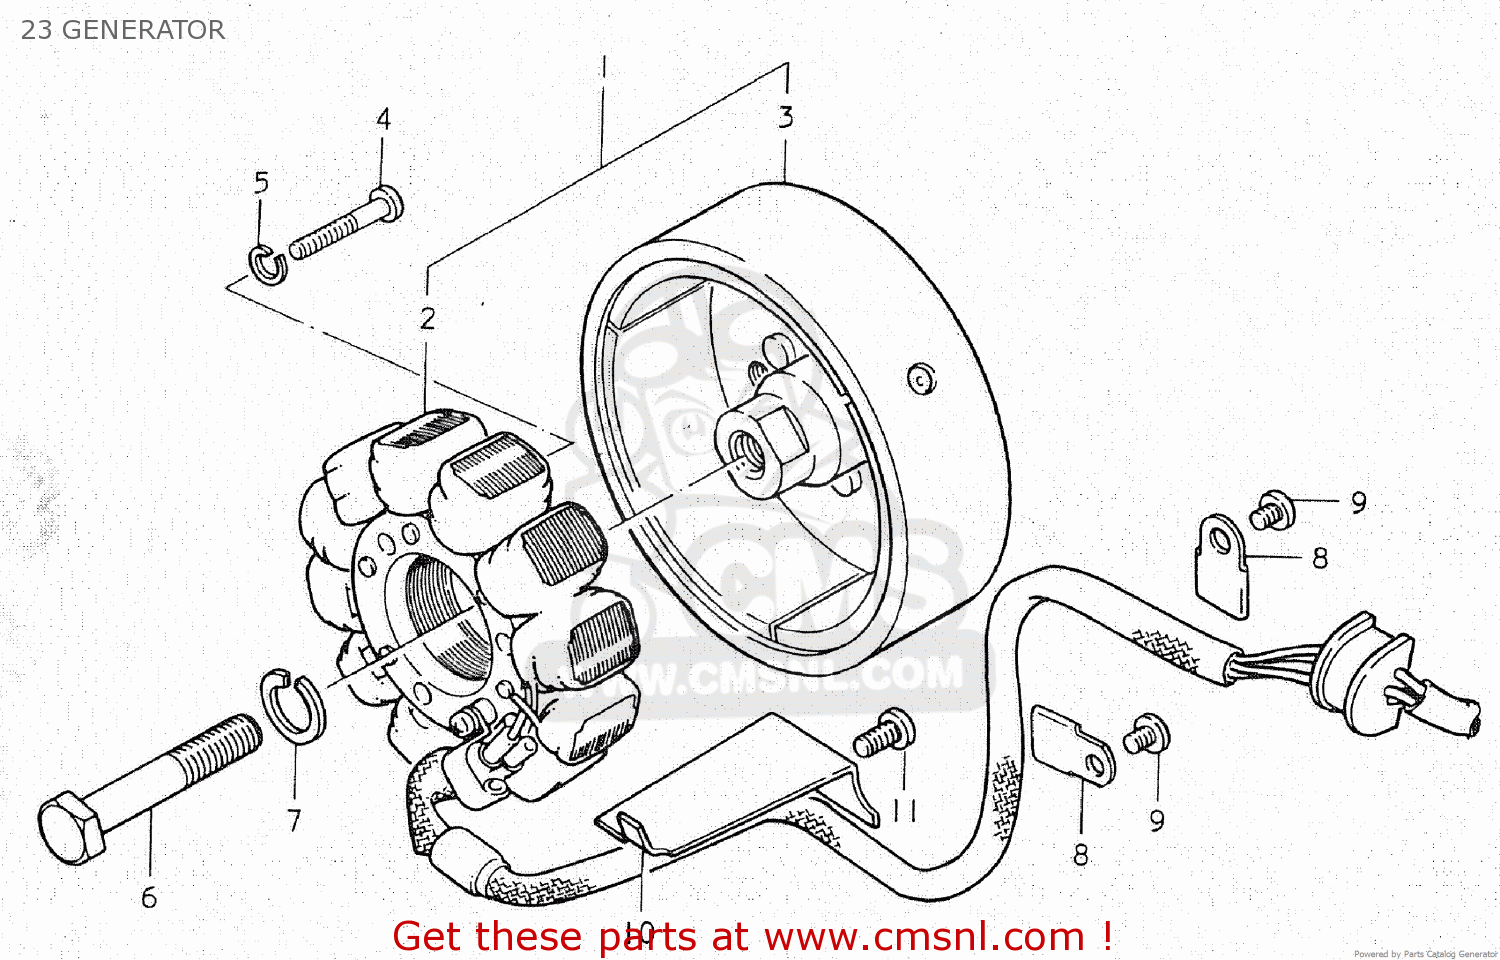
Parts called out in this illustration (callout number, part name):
1	GENERATOR ASSEMBLY
2	STARTER ASSY
3	ROTOR ASSEMBLY
4	SCREW
5	LOCK WASHER
6	BOLT 12X45
7	WASHER,LOCK 12
8	CLAMP,GENERATOR LEAD WIRE
9	SCREW
10	CLAMP,GENERATOR LEAD WIRE
11	SCREW
